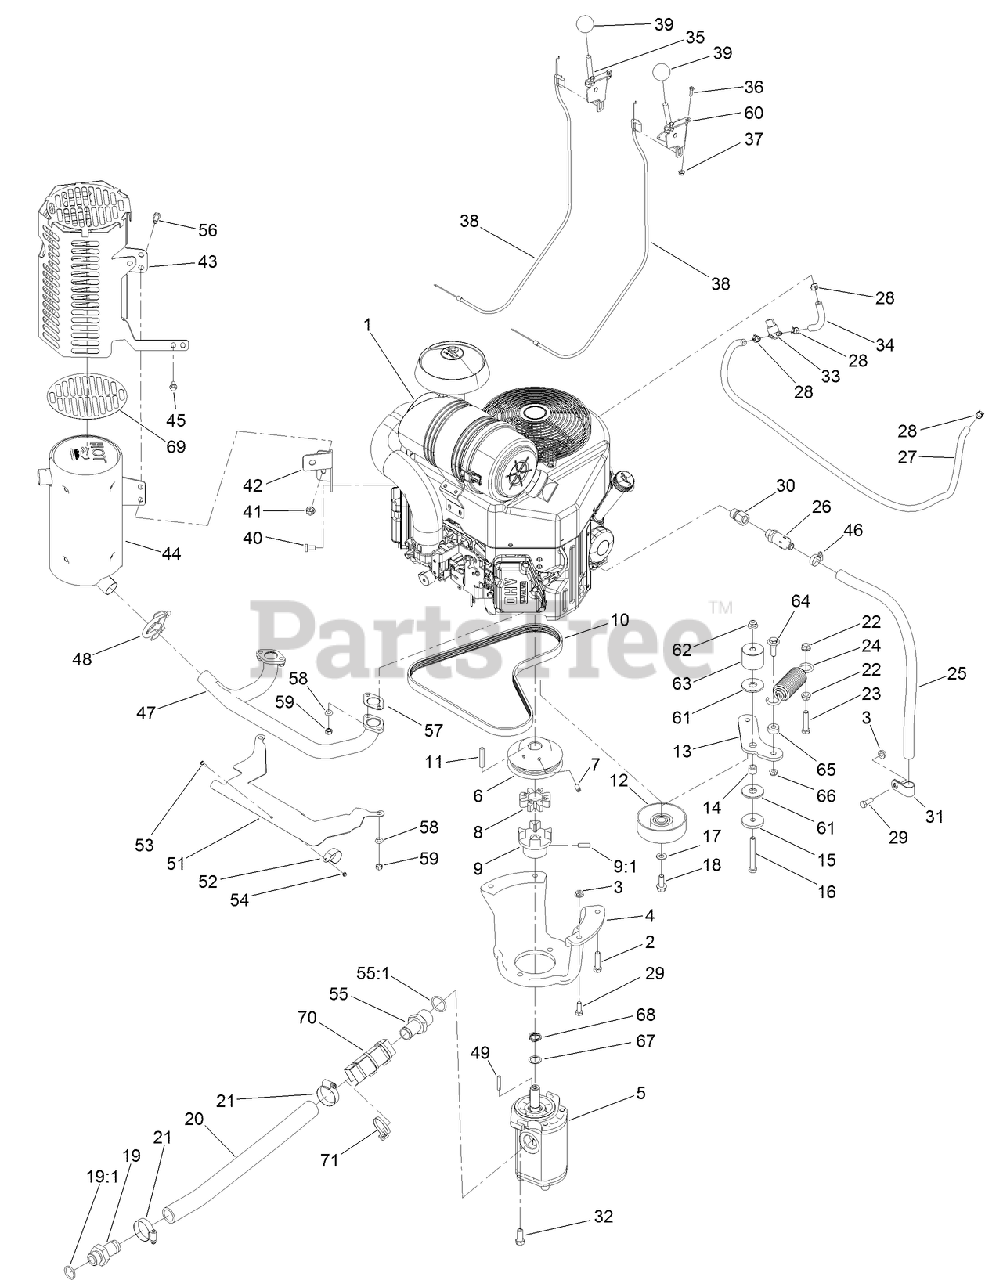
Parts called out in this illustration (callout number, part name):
1	ENGINE-KAWASAKI, FX730V
2	SCREW-HH
3	NUT-HF
4	MOUNT-PUMP
5	GEAR PUMP ASM
6	PULLEY-ENGINE
7	SCREW-SET, HSH
8	COUPLER-SPIDER
9	COUPLER-FLEX
9:1	SCREW-SET, HSH
10	BELT-V
11	KEY-SQUARE
12	PULLEY-IDLER
13	ARM-IDLER
14	BUSHING-LEVER, LIFT
15	WASHER-PLAIN
16	SCREW-HH
17	WASHER-FLAT
18	SCREW-HHF
19	FITTING
19:1	O-RING
20	HOSE-SUCTION
22	NUT-HHF, WHIZ
23	SCREW-HH
24	SPRING-EXTENSION
26	VALVE-DRAIN, OIL
27	HOSE-FUEL
28	CLAMP-HOSE
29	SCREW-HH
30	ADAPTER
31	CLAMP-R
32	SCREW-HH
33	VALVE-FUEL
34	HOSE-FUEL
35	LEVER-CONTROL
37	NUT-LOCK, FLANGE
38	CABLE-CONTROL
40	SCREW-HH
41	NUT-HF
42	BRACKET-MOUNT, MUFFLER
43	GUARD-MUFFLER
44	MUFFLER
45	SCREW-HHF
46	CLAMP-HOSE
47	MANIFOLD, MUFFLER
48	CLAMP-MUFFLER
49	KEY-SQUARE
51	PLATE-SHIELD, HEAT
53	SCREW-PAN
54	NUT-HEX
55	FITTING-STR
55:1	O-RING
56	SCREW-HH
57	GASKET-EXHAUST
58	WASHER-SPRING
59	NUT-HEX
60	LEVER-CONTROL
61	WASHER-FRICTION, COMPOSITE
62	NUT-HF, NI
63	SPACER-IDLER
64	SCREW-SHOULDER, HWH
65	SPACER
67	WASHER-THRUST
68	WASHER-WAVE
69	FOIL-GUARD
70	PROTECTOR-HOSE
71	TIE-CABLE
